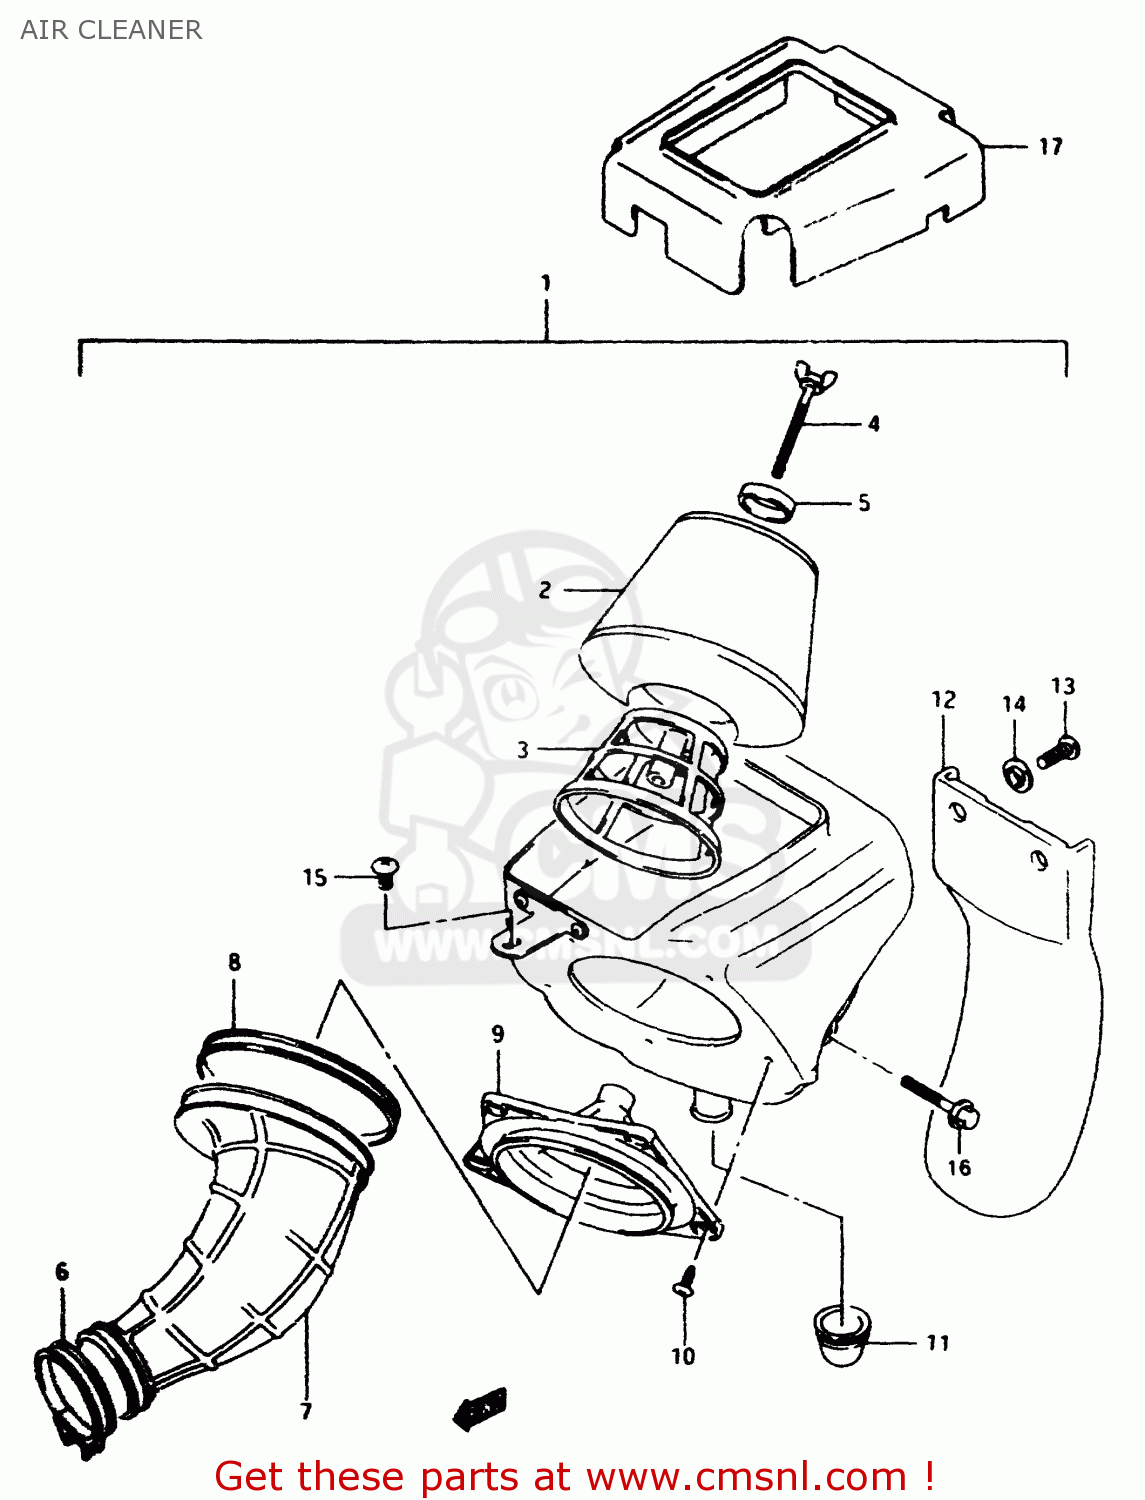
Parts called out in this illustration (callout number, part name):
1	CLEANER ASSY,AIR
2	FILTER ASSY
3	HOLDER
4	BOLT,WING
5	WASHER,AIR CLEANER
6	CLAMP
7	TUBE,OUTLET
8	CLAMP
9	BASE,FILTER
10	SCREW L:12
11	HOSE,AIR CLEANER DRAIN
12	GUARD,MUD
13	SCREW
14	COLLAR
15	SCREW 6X12
16	BOLT
17	MUD GUARD,B
